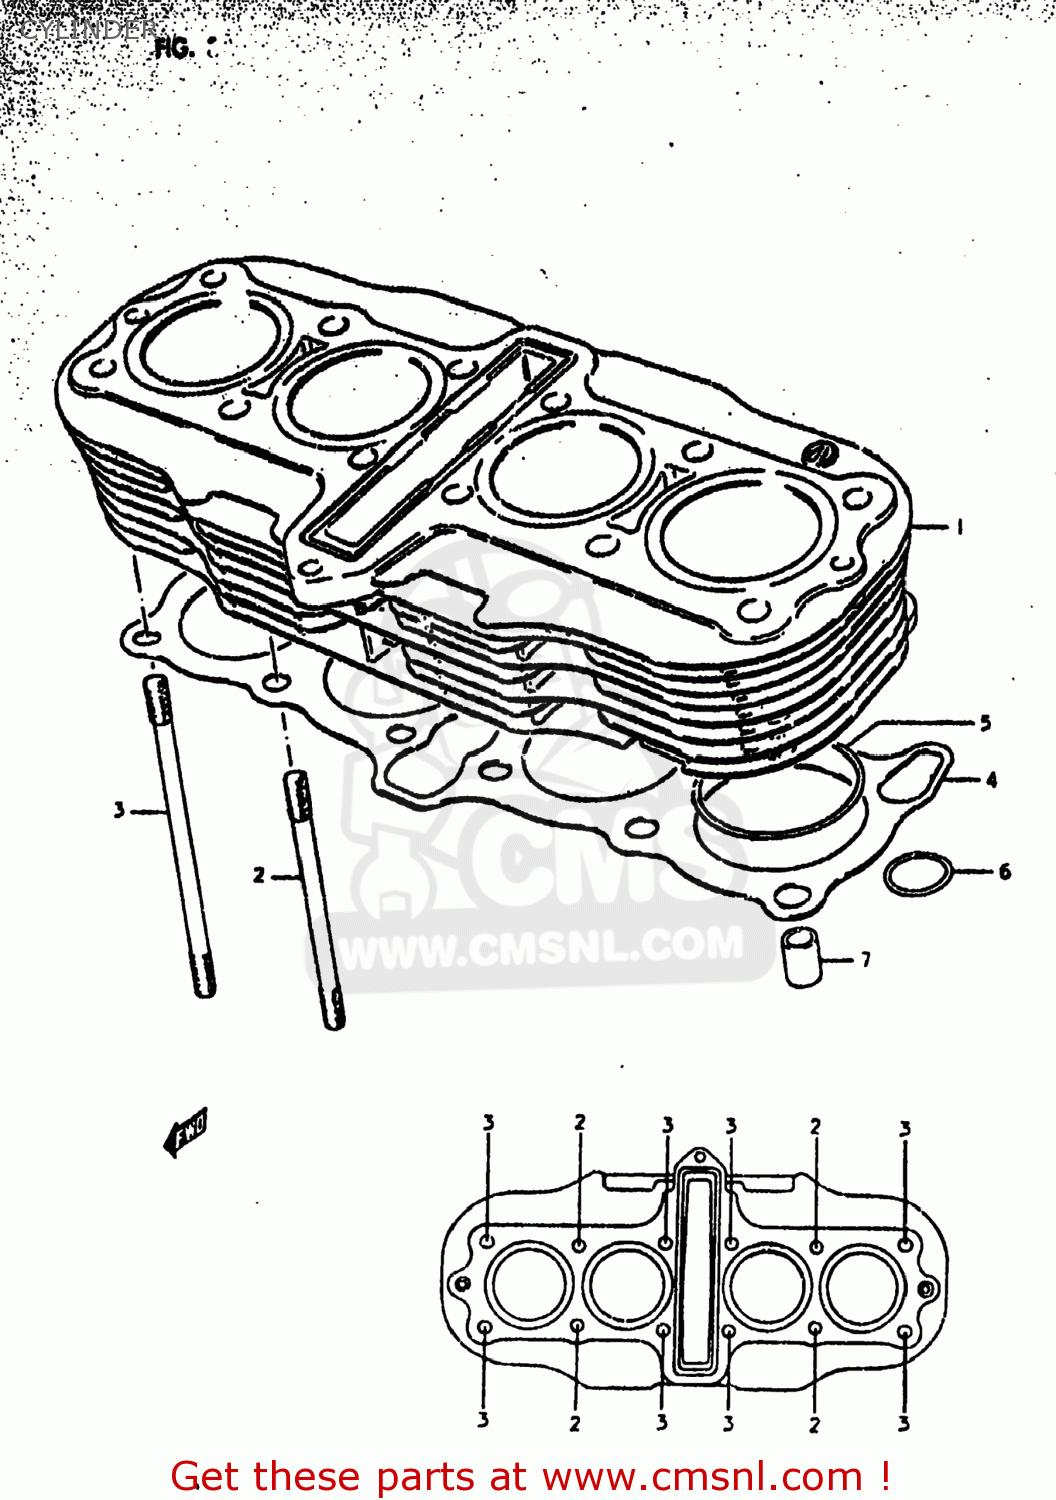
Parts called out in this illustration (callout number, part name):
1	CYLINDER
2	BOLT,STUD
3	BOLT,STUD
4	GASKET,CYLINDER (MCA)
5	O RING(D:2,ID:61)
6	O RING(D:2.4)
7	PIN
